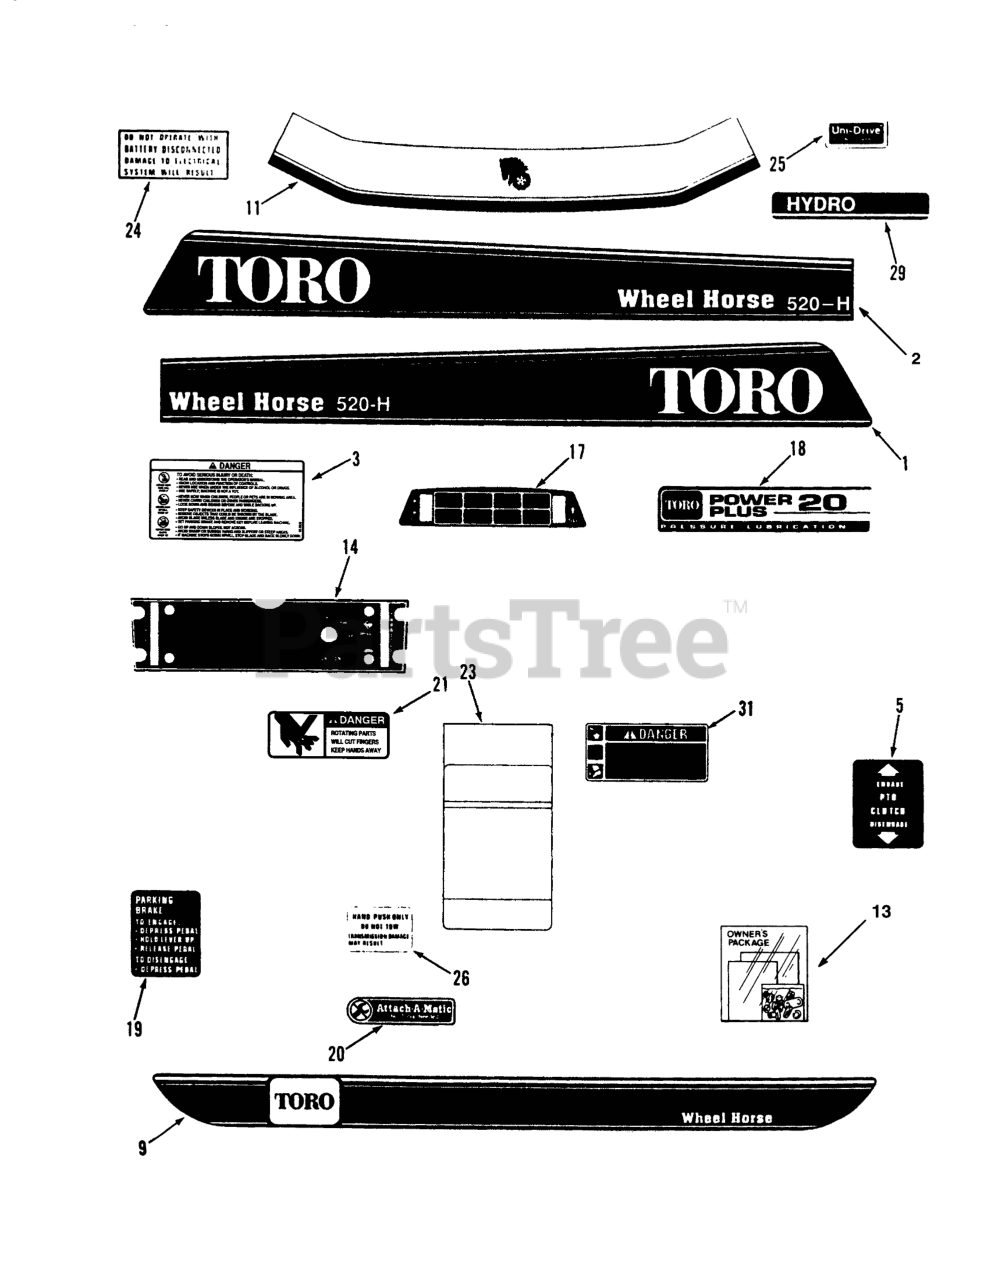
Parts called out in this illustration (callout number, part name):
1	DECAL HOOD 520H, RH
2	DECAL HOOD 520H, LH
3	DECAL - DANGER
5	DECAL PTO CLUTCH
9	DECAL-FENDER
11	DECAL-FRONT HOOD
13	Loose Parts Package
14	DECAL-FRONT PANEL
17	DECAL-IND LIGHTS
18	DECAL-PWR PLUS 20 PL
19	DECAL-PARKING BRAKE
20	Decal-Attac-O-Matic
21	DECAL - DANGER
23	Decal-Maintenance
24	DECAL ELECT SYSTEM
25	Decal-Unidrive
26	DECAL-DO NOT TOW
29	DECAL-MODEL HYDRO
31	DECAL-DANGER
